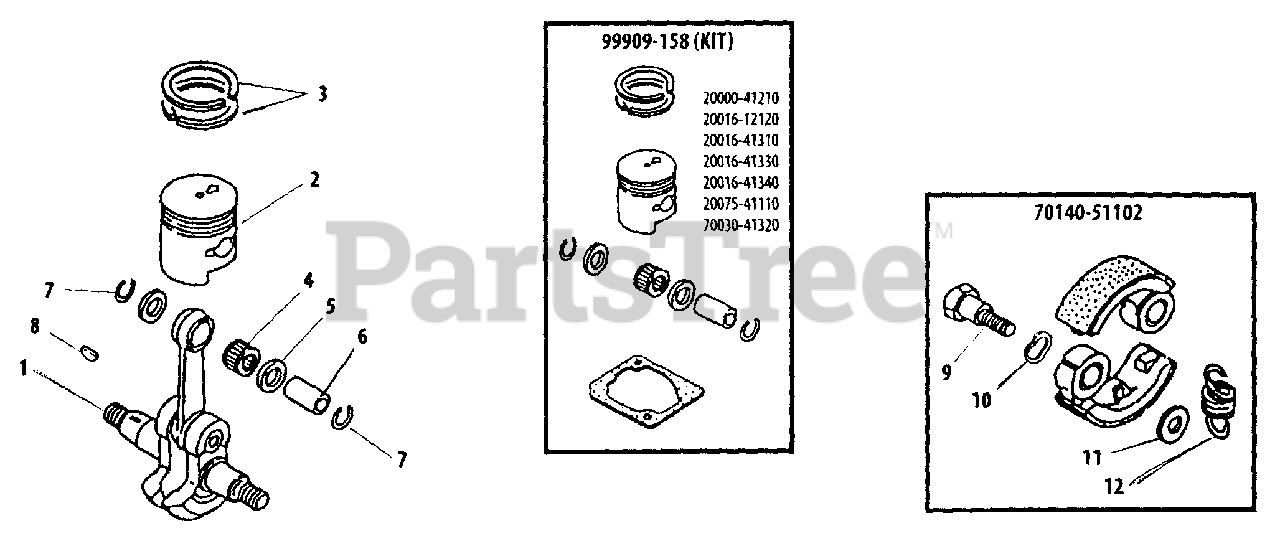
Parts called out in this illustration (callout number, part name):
1	CRANKSHAFT
2	PISTON
3	RING, PISTON
4	BEARING, NEEDLE
5	WASHER, THRUST
6	PIN, PISTON
7	RING, SNAP
8	KEY, WOODRUFF 3×10
9	BOLT, CLUTCH
10	WASHER, SPRING
11	WASHER 6 MM
12	SPRING, CLUTCH
70140-51102	CLUTCH ASSY
99909-158	PISTON ASSY
